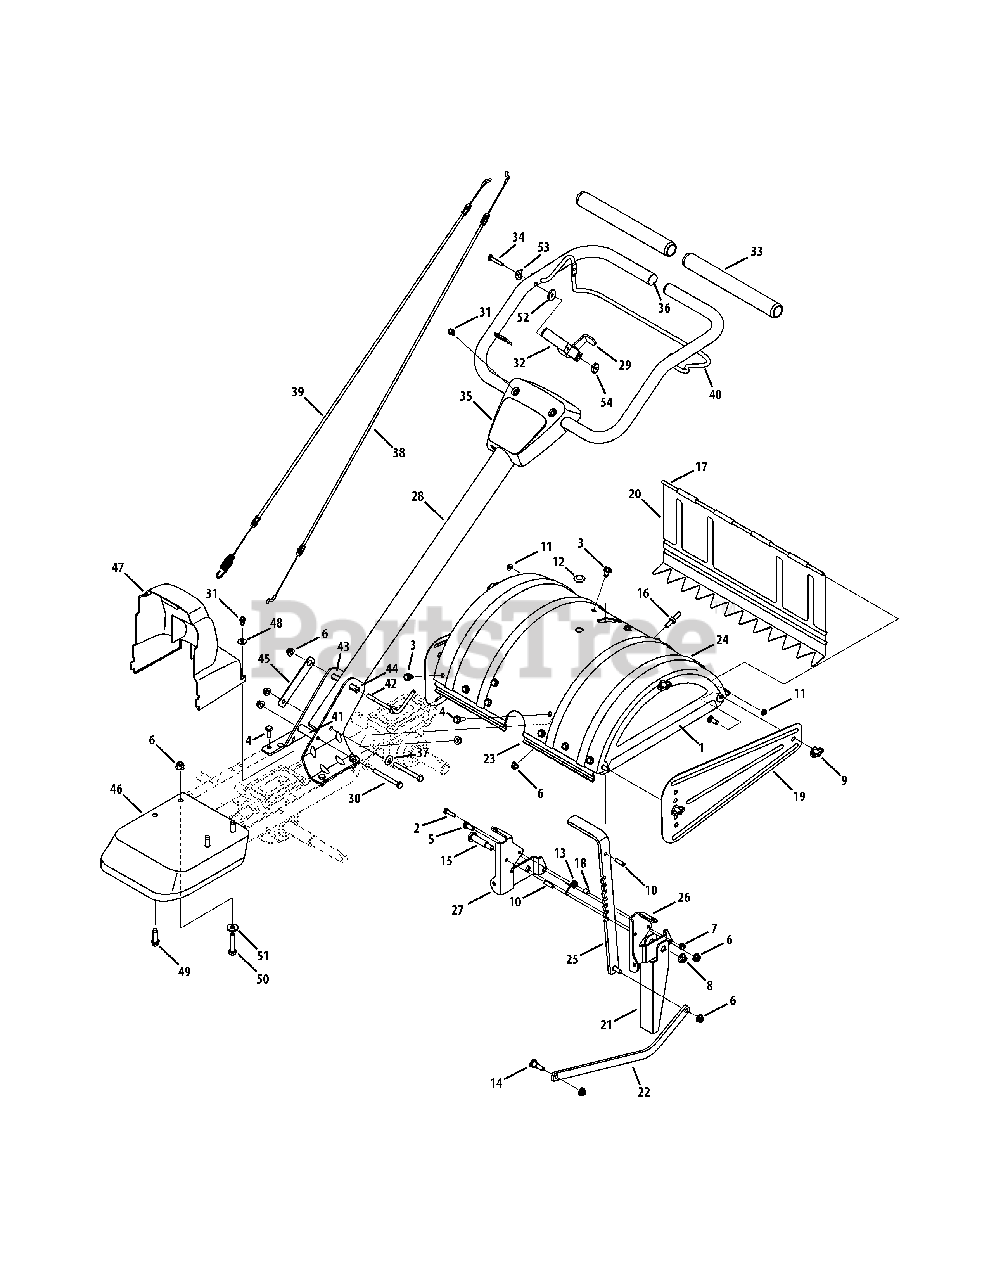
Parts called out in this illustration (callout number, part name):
1	End Cover Assembly
2	Hex Head Screw, 1/4-20 x 1
3	Hex Head Screw, 5/16-18 x .625
4	Hex Head Screw, 5/16-18 x .875
5	Hex Head Screw, 5/16-18 x .75
6	Nylon Hex Lock Nut, 5/16-18
7	Nylon Hex Lock Nut, 1/4-20
8	Flange Lock Nut, 3/8-16
9	Wing Nut, 5/16-18
10	Spirol Pin
11	Cap Nut, 1/4 Rod
12	Hole Plug
13	Torsion Spring
14	Shoulder Screw, .405 x .435 5/16-18
15	Shoulder Screw, .498 x 1.635
16	Stop Screw
17	Tiller Flap Rod
18	Spacer
19	Side Shield
20	Rear Tine Shield
21	Reverse Stop Arm
23	Tine Shield Mounting Bracket
24	Tine Shield
25	Adjustable Depth Bar
26	Tail Bracket, LH
27	Tail Bracket, RH
28	Upper Handle Assembly
29	Reverse Handle Assembly
30	Hex Head Screw, 5/16-18 x 3.00
31	Self-Tapping Screw, 1/4-20 x 1/2
32	Reverse Handle Grip
33	Foam Handle Grip
34	Hex Head Screw, 1/4-20 x 1.62
35	Handle Cover
36	Plug End
37	Bell Washer, .340 x .872 x .060
38	Reverse Cable
39	Forward Cable
40	Clutch Bail
41	Spacer, .322 x .625 x 2.00
42	Handle Crank
43	Handle Bracket, RH
44	Handle Bracket, LH
45	Retainer Nut Bracket
46	Front Bumper
47	Belt Cover
48	Flat Washer, .28 x .74 x .063
49	SEMS Screw, 3/8-16
50	Hex Head Screw, 5/16-18 x 1.50
51	Bell Washer, .827 x .331 x .098
52	Flat Washer, .265 x .938 x .120
53	Saddle Washer, .320 x .930 x .060
54	Spacer, .375 x .165
